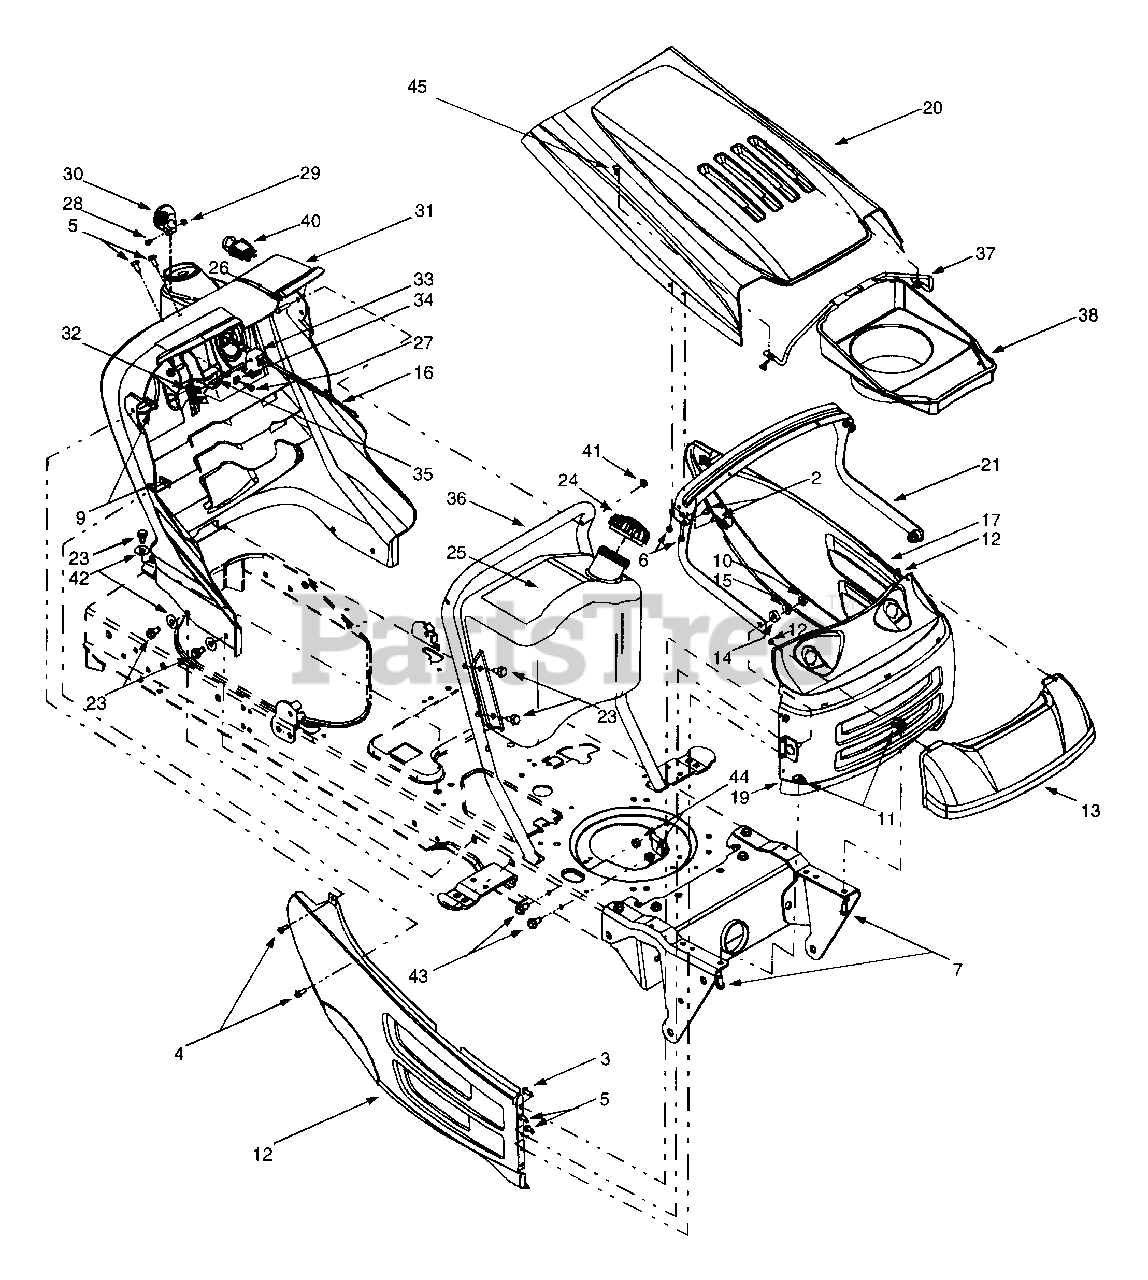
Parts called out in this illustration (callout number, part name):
2	Self-tapping Screw, 1/4-20 x .5
3	Hex Cap Screw, 1/4-20 x .62
4	Phillips Pan Screw, 1/4-20 x .75
5	Truss Phillips Screw, 1/4-20 x .625
6	Screw, #10-16 x .375
7	Hex Cap Screw, 5/16-18 x .75
9	U-type Speed Nut, 1/4-20
10	Flange Lock Nut, 3/8-16
11	U-nut, 5/16-18
12	Retainer Nut, 3/8
13	Headlight Lens (8-style)
14	Rubber Washer, .87 x .33
15	Bell Washer, .401 x .87 x .063
16	Choke Knob/Cable
24	Fuel Cap
25	Fuel Tank
26	Self-tapping Screw, 1/4-20 x 1.25
27	Self-tapping Screw, 1/4-15 x .75
28	Truss Phillips Screw, #8-32 x .375
29	Hex Nut, #8-32
30	Throttle Control Knob
31	Dash Panel (8-style)
32	Plastic Plug
33	Parking Brake Button
34	Flat Washer, 9/32 x 1/2 x 1/16
35	Pivot Rod
38	Heat Shield (8-style, OHV V-twin)
40	Electric PTO Switch
41	Hex Flange Lock Nut, 1/4-20
42	Flat Washer, .349 x 1.0 x .063
43	Screw, 5/16-18 x .875 (Grade 5)
44	Hex Nut, 5/16-18
45	Ratchet Clip
